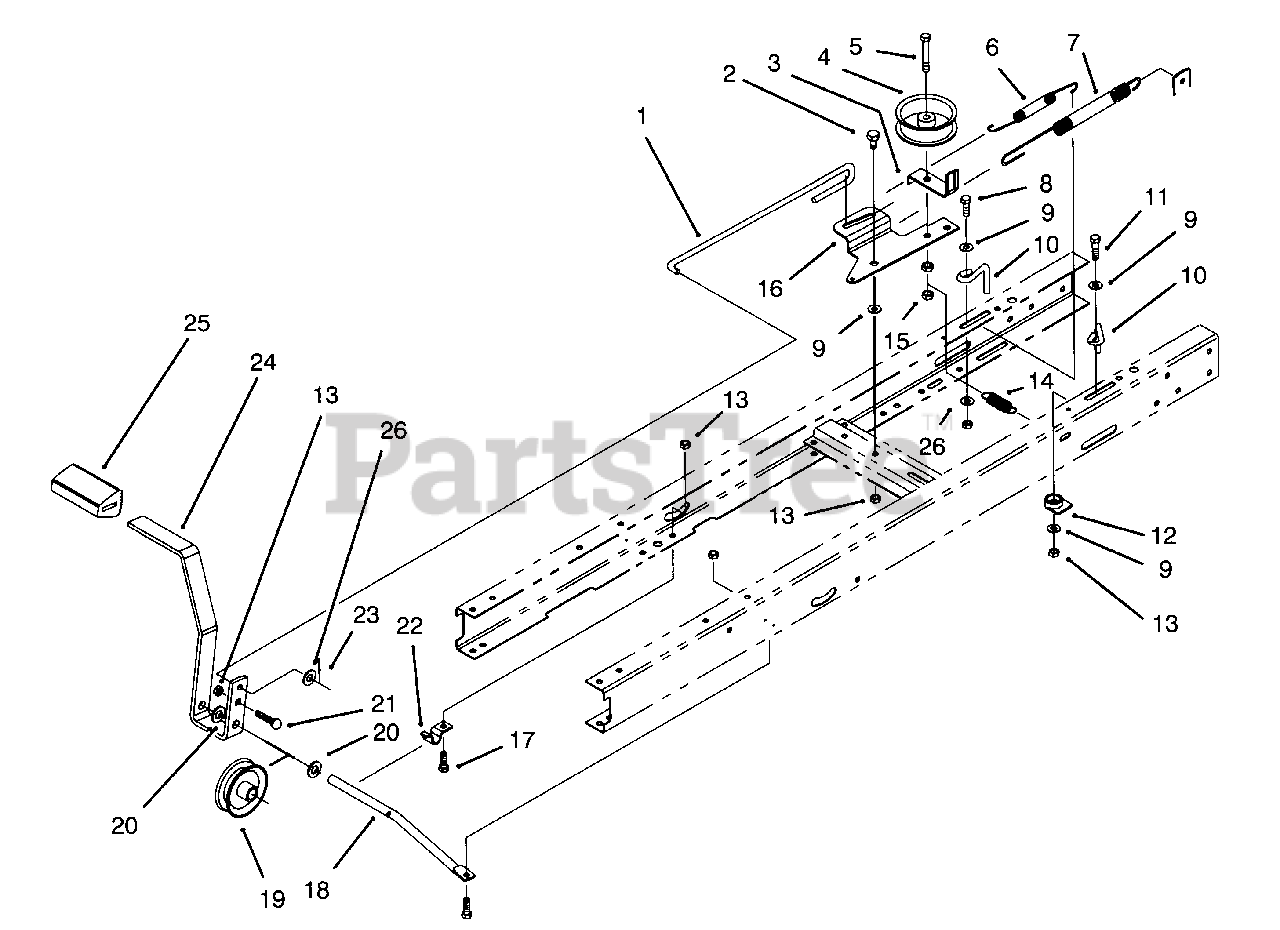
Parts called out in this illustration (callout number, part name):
1	Rod-Clutch/Brake
2	Bolt-Shoulder
3	Guide-Idler Belt
4	Pulley-Flat Idler
5	Screw-Hex Hd. Cap
6	Spring-Pedal Return
7	Spring-Brake
8	Screw-Hex Hd. Cap
9	Washer-Flat
10	Guide-Trans. Belt
11	Screw-Hex Hd. Cap
12	Guide-Cable
13	Nut-Lock
14	Spring-Extension
15	Nut-Lock
16	Arm-Idler
17	Screw-Hex Hd. Cap
18	Rod-Pedal Pivot
19	Pulley-Cable
20	Washer-Flat
21	Bolt-Carriage
22	Clamp-Shift Pivot
23	Pin-Cotter
24	Pedal-Clutch/Brake
25	Pad-Pedal
26	Washer-Flat
